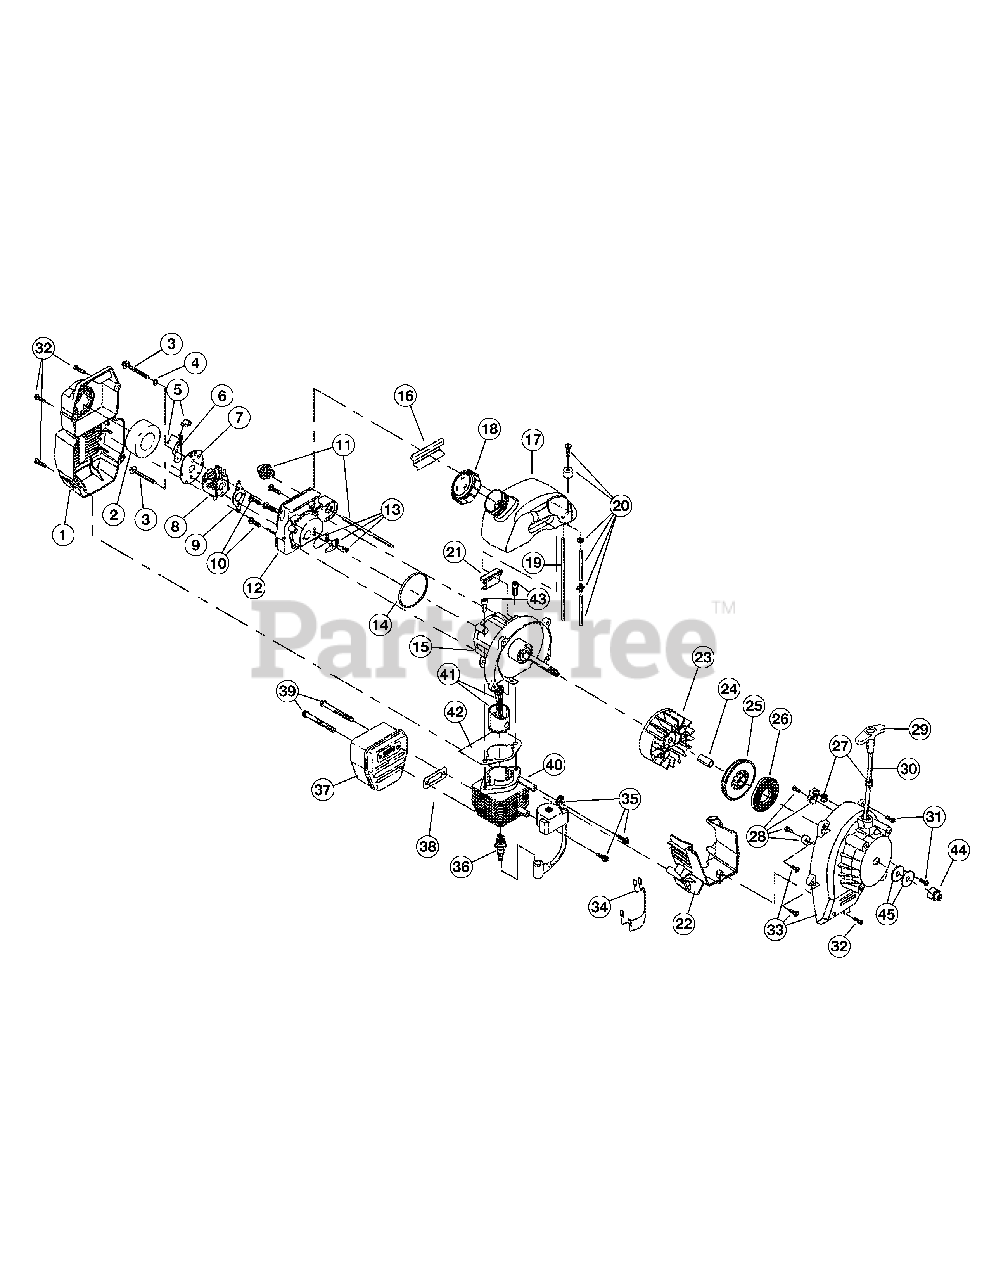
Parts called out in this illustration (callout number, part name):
1	Air Cleaner/Muffler Cover Assembly
2	Air Cleaner Filter
3	Carburetor Mounting Screw
4	Wavey Washer
5	Choke Knob and Screw
6	Choke Lever Assembly
7	Choke Lever and Plate
8	Carburetor Assembly
9	Carburetor Gasket
10	Carb Mount Screw
11	Primer and Hose Assembly
12	Carb Mount Assembly
13	Reed Assembly
14	O-Ring
15	Crank Case Service Assembly
16	Rear Mounting Pad
17	Fuel Tank Assembly
18	Fuel Cap Assembly
19	Fuel Return Line
20	Fuel Line Assembly
21	Front Mounting Pad
22	Shroud Extension
23	Flywheel Assembly
24	Spacer
25	Recoil Pulley
26	Recoil Spring
27	Rope Guide
28	Pulley Retainer Assembly
29	Pull Handle
31	Housing Screw
32	Cover Screw
33	Starter Housing Assembly
34	Wire Lead Assembly
35	Module Assembly MA-57 792-10527A
35	Module Assembly M-56 7181B
35	Module Assembly MA-90 7181B-1
36	Spark Plug
37	Muffler Assembly
38	Exhaust Gasket
39	Muffler Mounting Bolt Assembly
40	Cylinder Assembly
41	Piston and Rod Assembly
42	Cylinder Gasket
43	Cylinder Bolt
44	Crankshaft Extension
45	Washer
